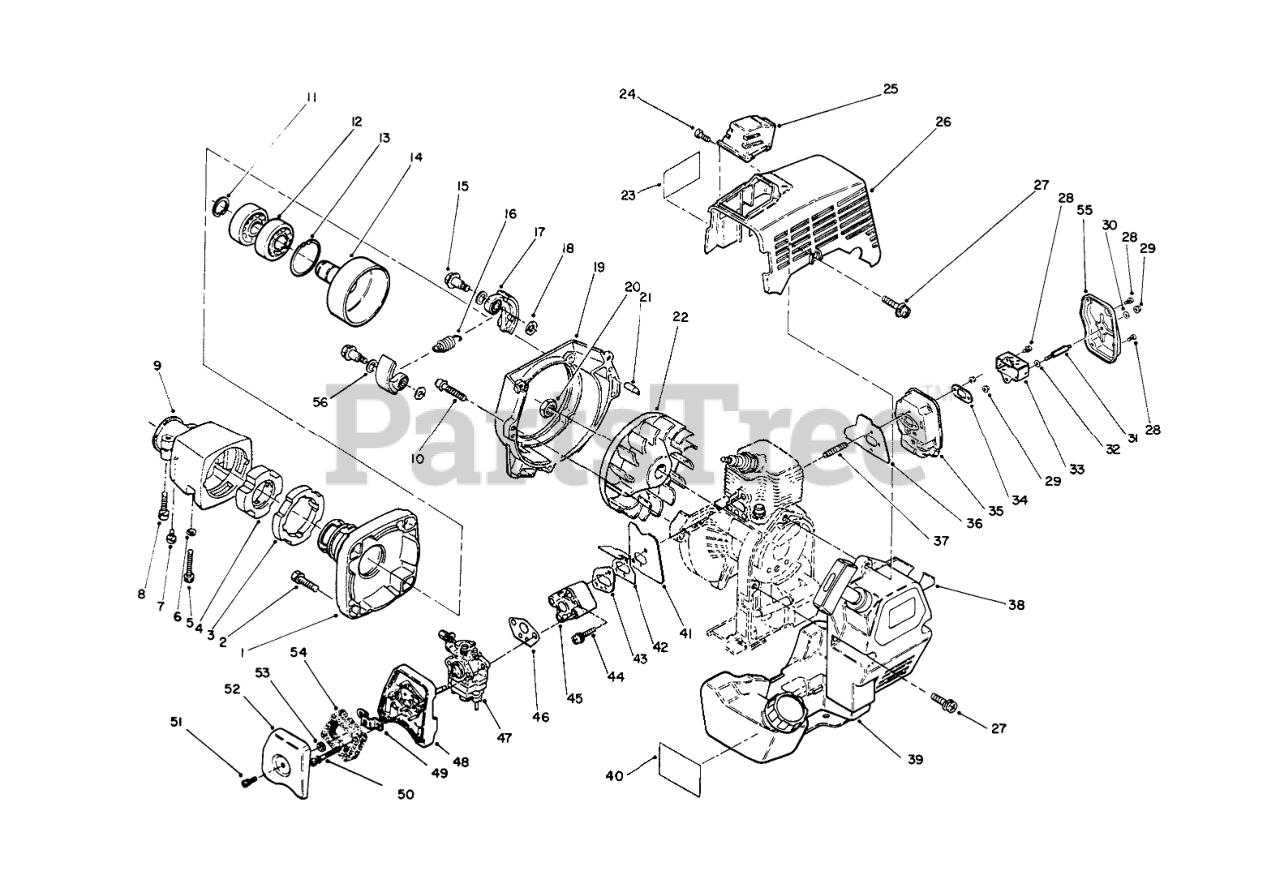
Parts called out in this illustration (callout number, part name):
1	Case-Clutch
3	RUBBER, CUSHION (A)
4	RUBBER, CUSHION (B)
6	Washer
7	Screw/Washer
8	BOLT-WASHER/ENG
9	Holder
11	SNAP RING
12	BALL BEARING
13	SNAP RING
14	DRUM, CLUTCH
15	CLUTCH BOLT
16	CLUTCH SPRING
17	CLUTCH SHOE
18	WASHER
19	FAN CASE
23	DECAL-SURFACE, HOT
24	SCREW & WASHER
25	SPARK PLUG GUARD
26	TOP COVER
27	SCREW & WASHER
28	SCREW & WASHER
29	MUFFLER FLANGE NUT
30	GASKET
31	DUAL BOLT
32	WASHER
33	Baffle
34	Plate
35	MUFFLER ASSEMBLY
36	MUFFLER GASKET
37	STUD BOLT
38	Starter-Recoil
39	FUEL TANK CAP
40	DECAL - FUEL TANK
41	INSULATOR GASKET
42	PLATE
43	INSULATOR GASKET
44	SCREW & WASHER
45	INSULATOR
46	CARBURETOR GASKET
47	Carburetor Assembly
48	CLEANER CASE
49	BRACKET
50	SCREW W/ WASHER
51	SCREW & WASHERE
52	CLEANER COVER
54	CLEANER ELEMENT
55	Cover-Muffler
56	Washer-Wave
